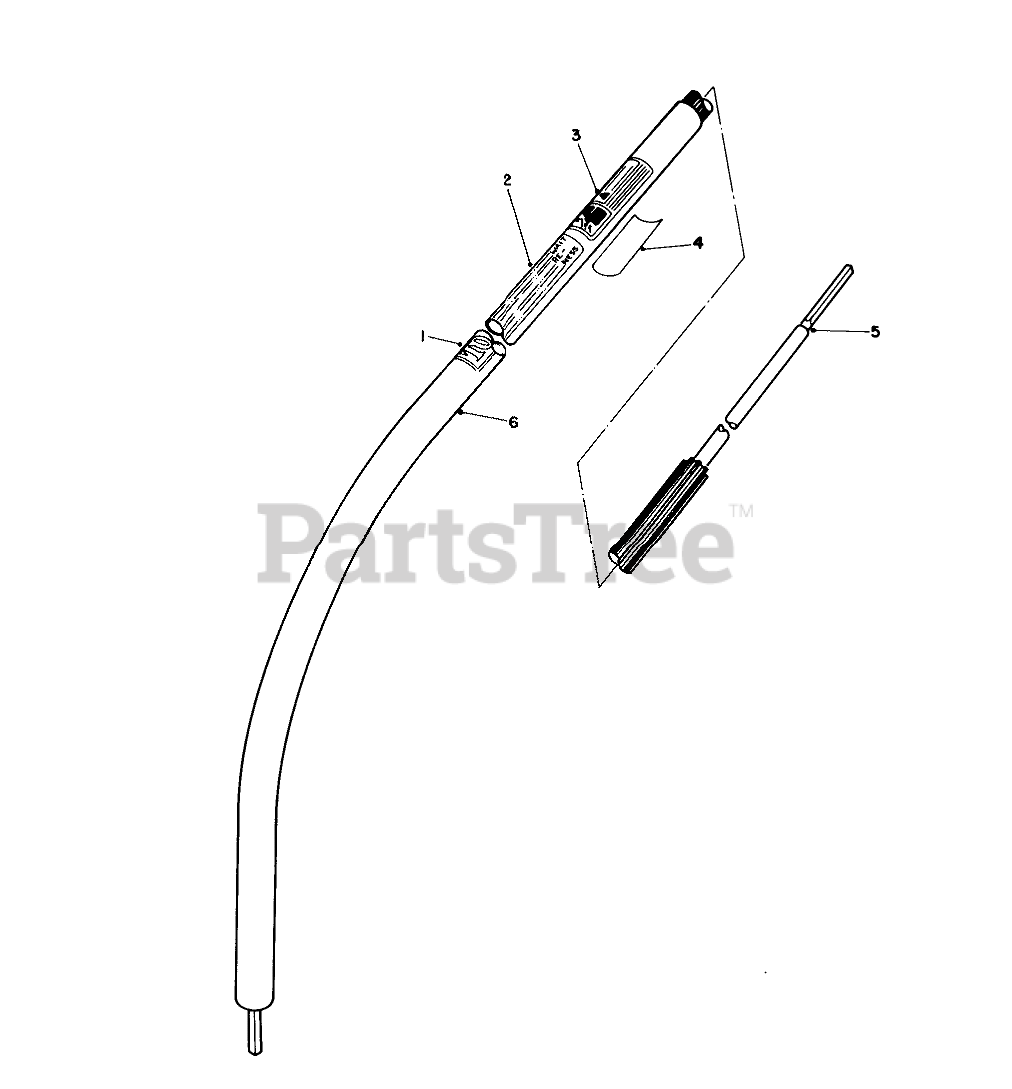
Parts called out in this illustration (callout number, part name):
1	Decal
2	Decal
3	Decal Warning
4	REP. SERIAL PLT
5	Shaft-Flex Assembly
6	Tube-Lower Shaft (Incl. Ref. #2&3)
